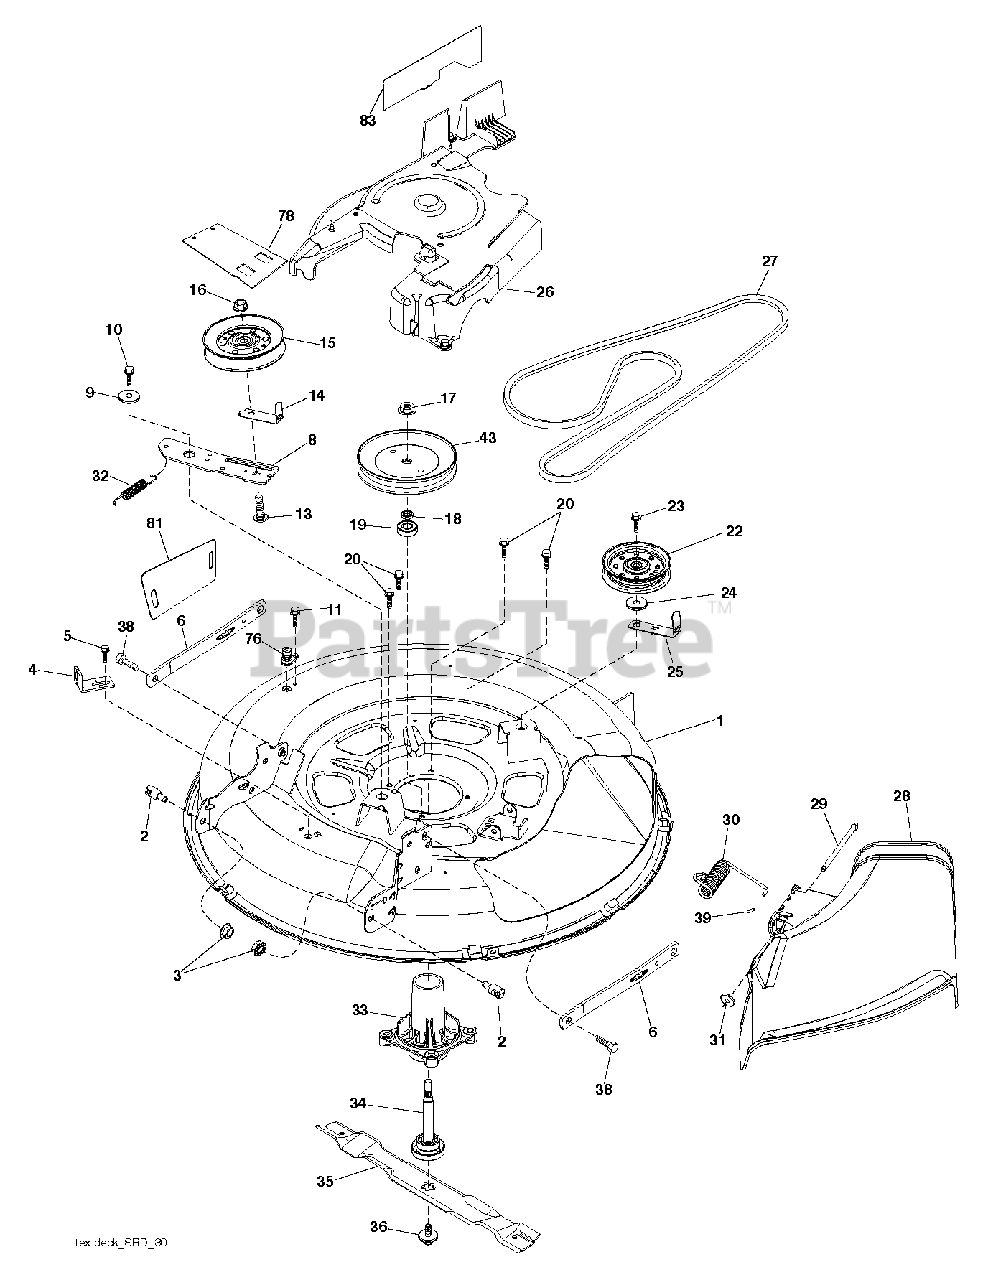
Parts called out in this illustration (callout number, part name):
1	DECK.WELDMENT.PNT.30"SRD
2	STUD.FASTNER.W/ANTI-ROTATE
3	NUT LOCK HEX FLANGE 5/16-18
4	BRACKET.CLUTCH.CABLE
5	BOLT.5/16HEX.WHS.HD
6	ARMS.SUSP.MOWER.REAR.SRD
8	ARM.IDLER.30"SRD
9	SPACER.RETAINER
10	SCREW 3/8-16X1
11	SCREW.1/4-20X5/8
13	BOLT.3/8-16X1.50
14	KEEPER, BELT IDLER
15	PULLEY.IDLER.4.25
16	NUT LOCK FLG 3/8-16 UNC
17	NUT.FLANGE.LOCK.TOP
18	WASHER.SPACER.MANDREL
20	SCREW, WASHER HEAD
22	PULLEY.IDLER.FLAT.46.PR.DR.
23	SCREW LT
24	WASHER
25	KEEPER.BELT.30"SRD
26	COVER.ASM.MANDREL.30"
27	V-BELT.DRIVE.MOWER.30"
28	SHIELD.DEFLECT.MWR.30S.BLACK
29	PIN.HINGE.30".SRD
30	SPRING.TORSION.DEFLECT
31	NUT PUSH M
32	SPRING.MOWER.DRIVE.ELECTRIC
33	HOUSING.MANDREL.4PT.
34	SHAFT.ASM.MDRL.N/GREASE.38
35	BLADE, MULCH.LRV30
36	BOLT.WASHER.ASM.7/16-2
38	BOLT.SHOULDER
39	CAP-SLEEVE LT
43	PULLEY, MANDREL 6.5 PD
76	PORT.WASHOUT
78	GUARD ARM CLUTCH
81	SHIELD SUSPENSION
